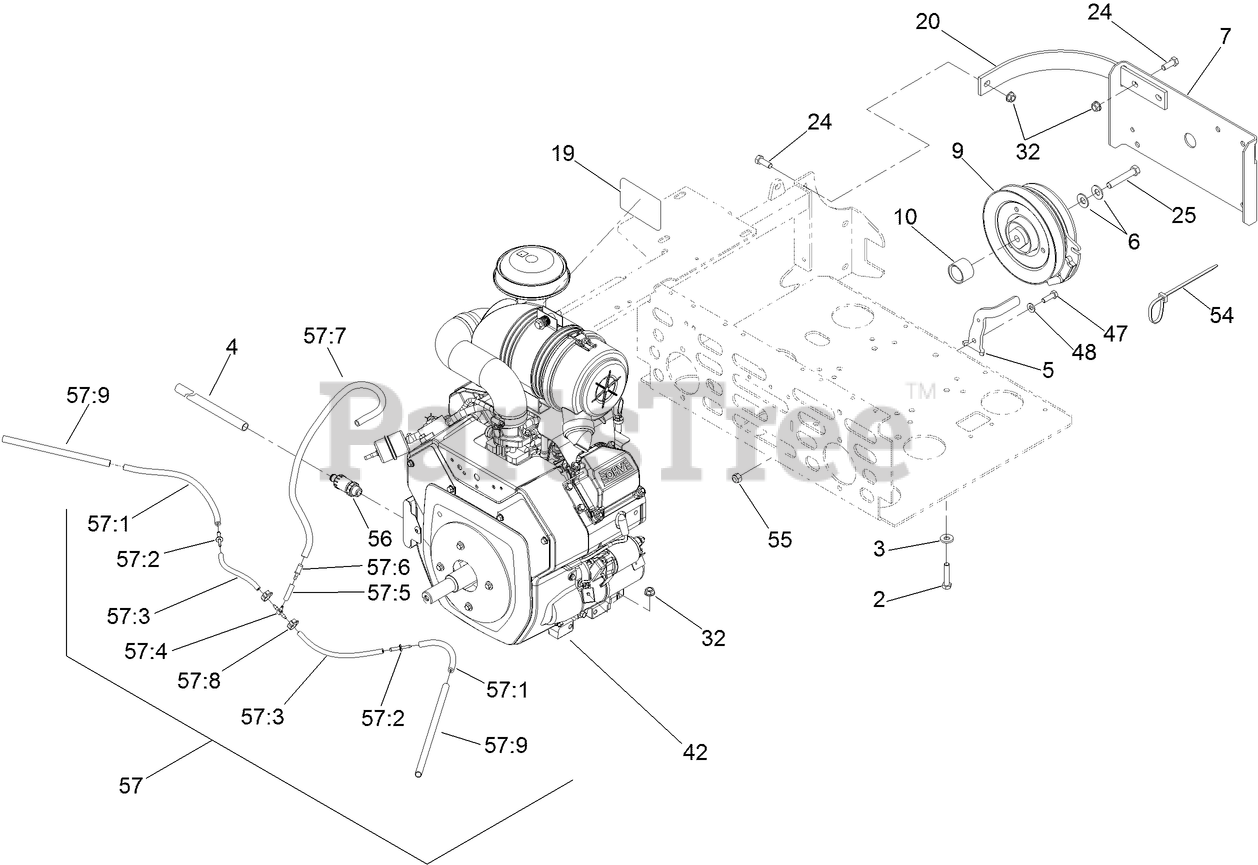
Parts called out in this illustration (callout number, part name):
2	SCREW-HH
3	WASHER-BELLEVILLE
4	TUBE-DRAIN, OIL
5	ANCHOR-CLUTCH
6	WASHER-SPRING
7	GUARD-CLUTCH
9	CLUTCH
10	SPACER-CLUTCH
20	STRAP-GUARD
24	SCREW-HH
25	SCREW-HH
32	NUT-HHF, WHIZ
47	SCREW-HH
48	WASHER-SPRING
54	TIE-PLASTIC
55	NUT-LOCK, NI
56	VALVE-DRAIN, OIL
57	VENT HOSES ASM
57:1	HOSE-FUEL
57:2	ADAPTOR-ORIFICE
57:3	HOSE-FUEL
57:4	FITTING-TEE
57:5	HOSE-FUEL
57:6	FITTING-STRAIGHT
57:7	HOSE-FUEL
57:8	CLIP-CONDUIT, NAIL
57:9	COVER HOSE
